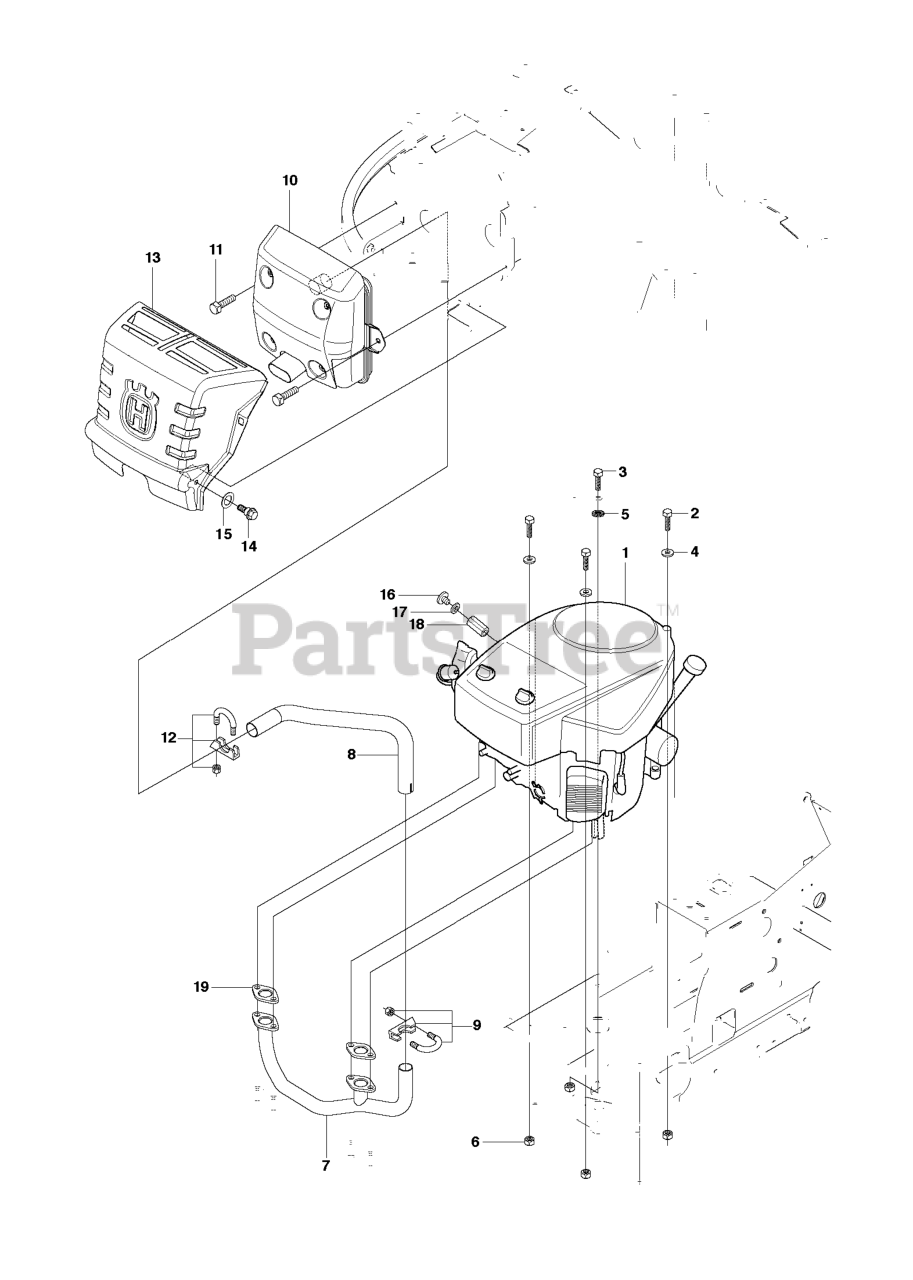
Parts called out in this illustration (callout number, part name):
4	WASHER BRB 8.4X17
6	LOCKNUT M8
8	PIPE KAWASAKI
9	CLAMP
12	CLAMP
13	HEAT PROTECTOR
15	SPRINGWASHER
